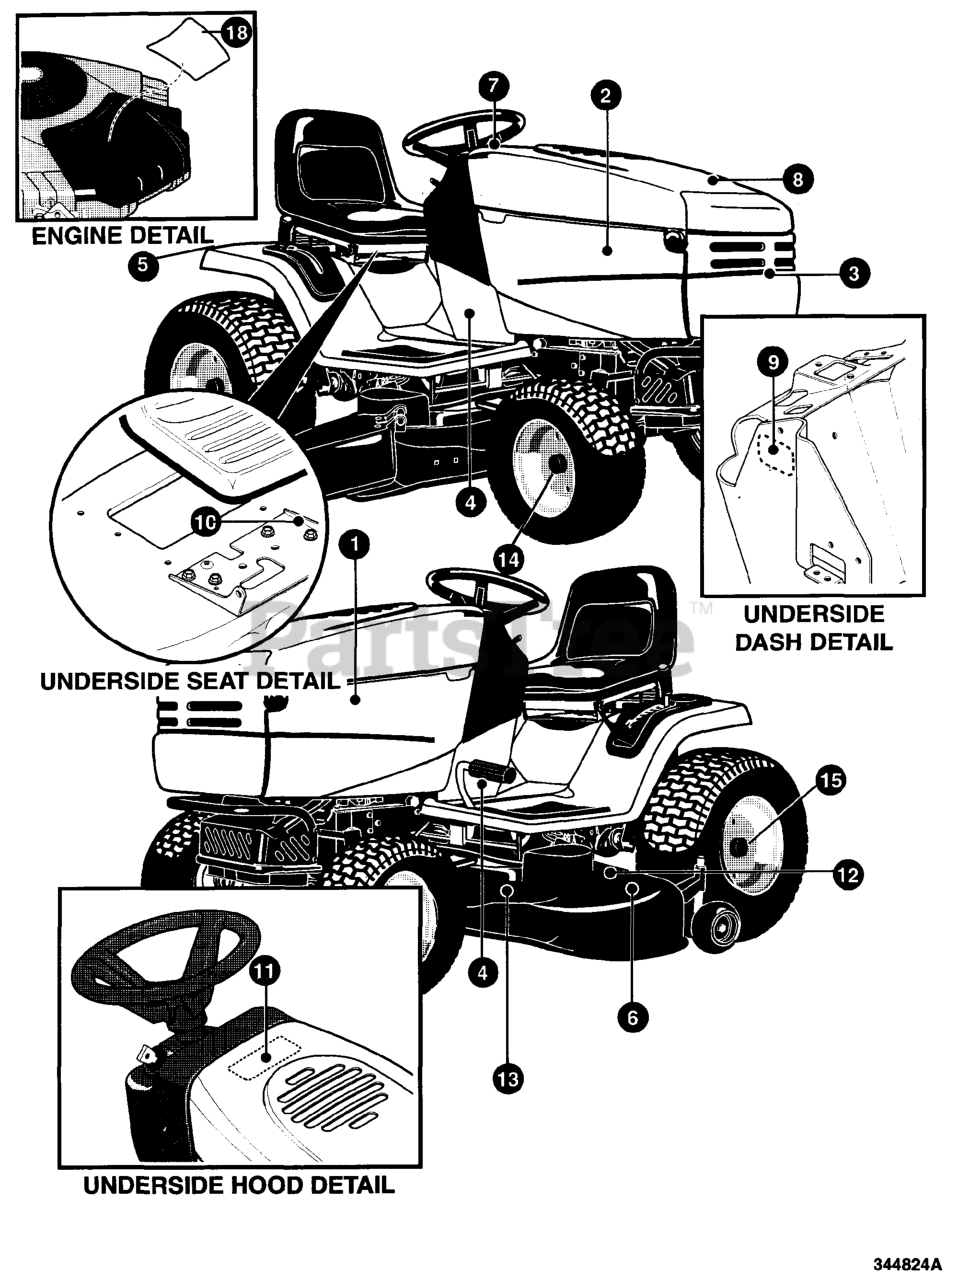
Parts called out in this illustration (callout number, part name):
1	DECAL, 20/46 SCOTTS -LH
2	DECAL, 20/46 SCOTTS -RH
3	DECAL, PIN STRIPS, SCOTTS
4	DECAL, POW BY INTEK OIL FIL SYS
5	DECAL, REAR SEAT DECK SCOTTS
6	DECAL, CUTTING DECK
7	DECAL, CUST. CARE CENTER
8	DECAL, EMBLEM HOOD SCOTTS
9	DECAL, PUSH BUTTON RESET
10	NOT A SERVICABLE PART
11	DECAL, MAINTENANCE 20 INTEK
12	DECAL, DECK LEVEL PROCEDURES
13	DECAL, DECK ROUTING 46"
14	HUB CAP
15	HUB CAP
18	DECAL, ENG. SCOTTS 20 INTEK
